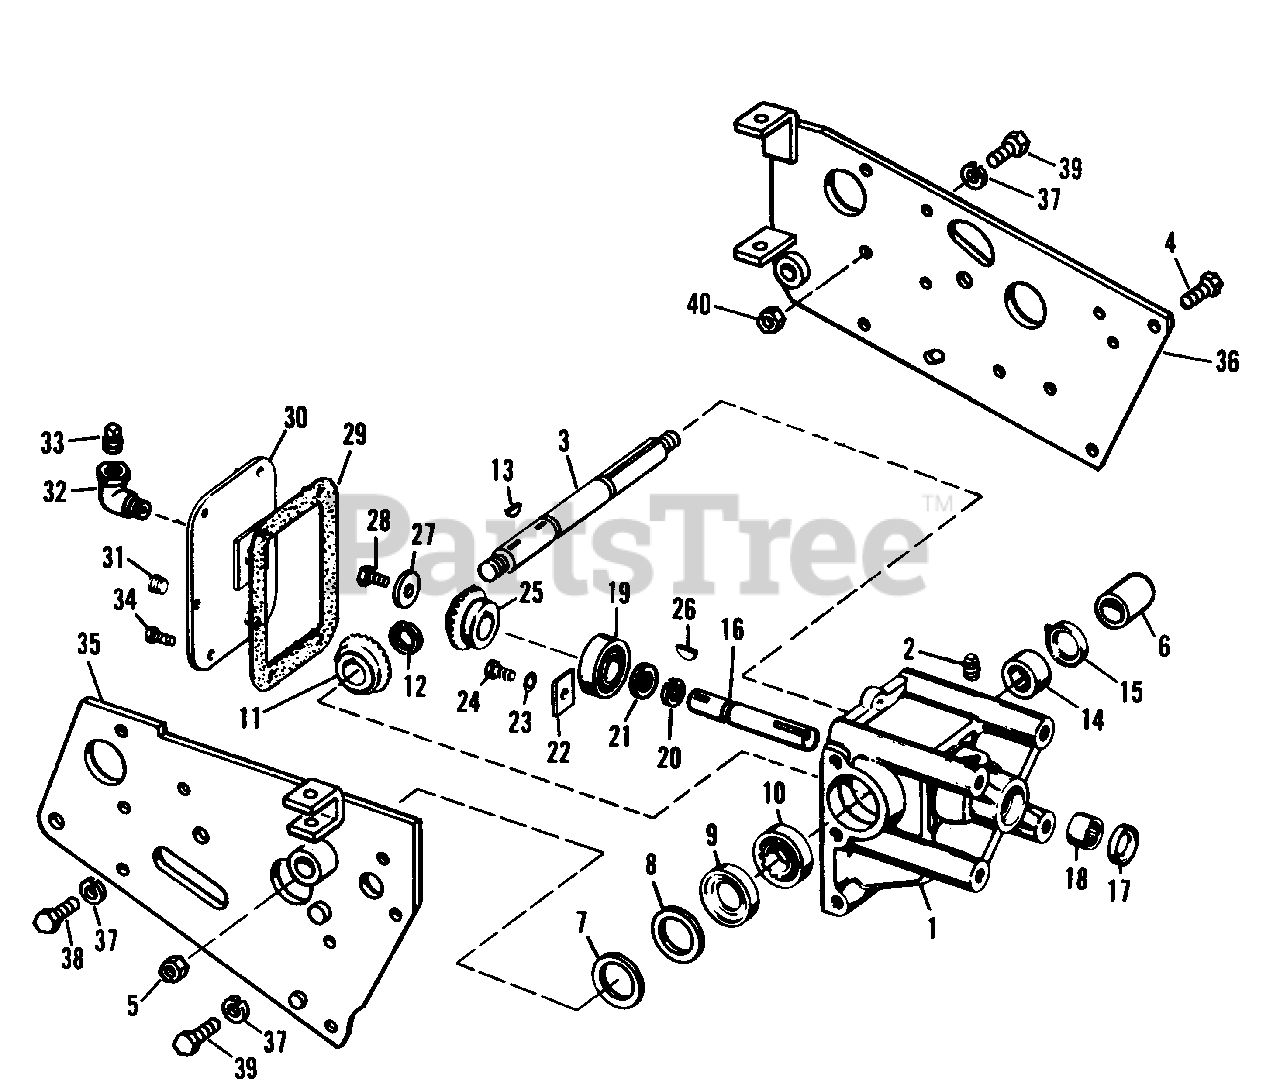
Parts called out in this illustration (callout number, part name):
1	Bevel Gear Housing, w/Bearings
2	Pipe Plug
3	Driven Shaft
4	Hex Cap Screw, 7/16"-14 x 1-1/4"
5	Hex Jam Nut
7	Shim (As Required)
10	Ball Bearing
11	Bevel Driven Gear
12	Retaining Ring
14	Needle Bearing
16	Drive Shaft
18	Needle Bearing
19	Ball Bearing
20	Retaining Ring
22	Bearing Clamp Plate
23	Lock Washer, 5/16"
24	Hex Capscrew, 5/16"-18 x 5/8"
25	Bevel Driven Gear
28	Hex Capscrew, 5/16"-18 x 3/4"
30	Housing Cover Assembly
31	Pipe Plug
32	Street Elbow
33	Pipe Plug
34	Hex Cap Screw, 1/4"-20 x 5/8"
35	R.H. Side Plate
36	L.H. Side Plate
37	Lock Washer, 7/16"
38	Hex Cap Screw, 7/16"-14 x 1"
39	Hex Cap Screw, 7/16"-14 x 1-1/4"
40	Full Hex Nut, 7/16"-14
